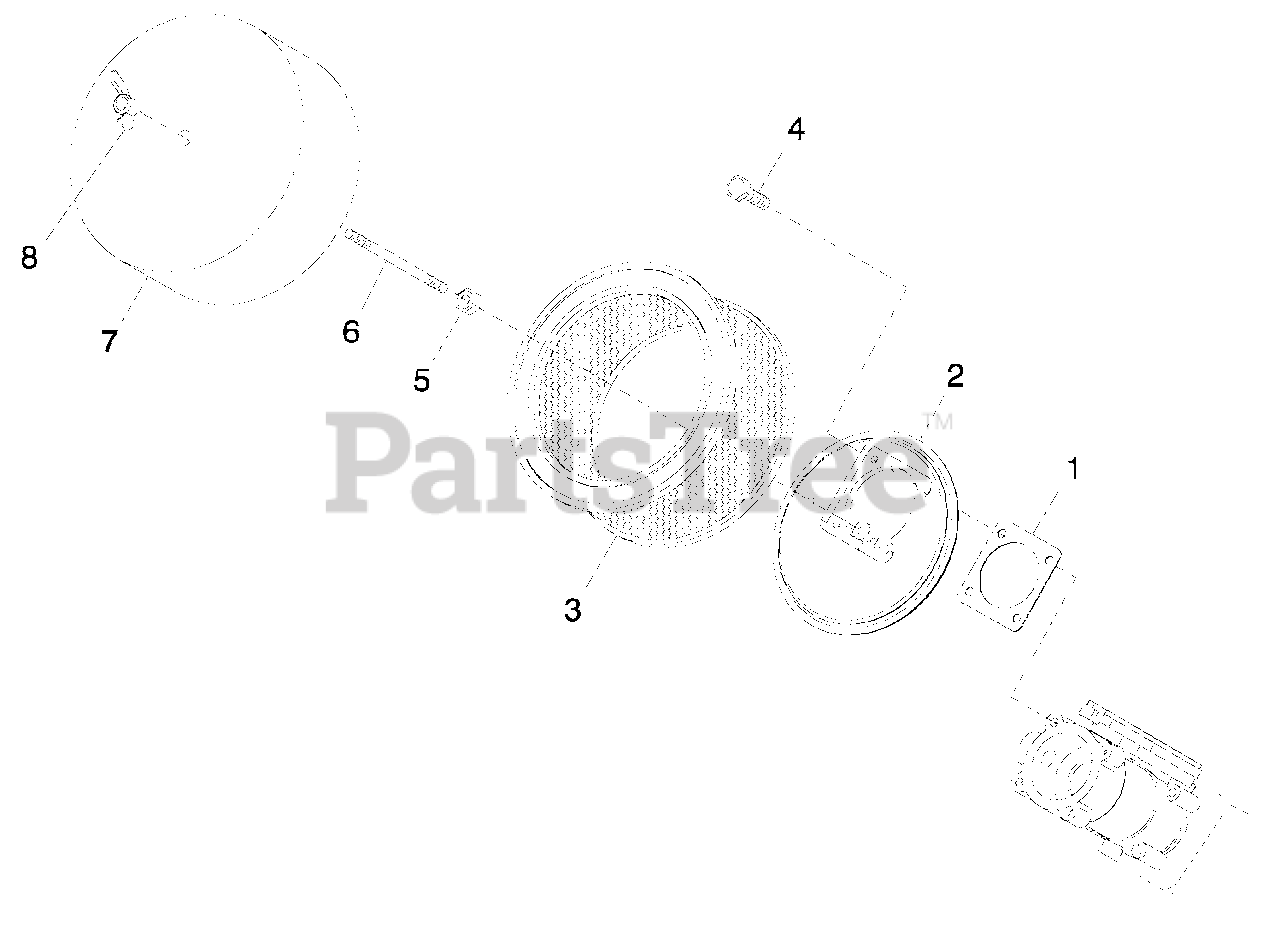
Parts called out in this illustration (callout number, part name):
1	GASKET BOSCH 32 & 40
2	ADAPTER CARBURETOR W/PVC CONN
3	ELE MENT AIR CLEANER
4	SCREW HHC M5-0.8X 16 G8.8
5	NUT HEX 1/4-20 STEEL
6	STUD TH 1/4-20 X 4-1/2 G2ZNC
7	PLATE, AIR CLEANER TOP 2.4L
8	NUT WING 1/4-20 NYLK
